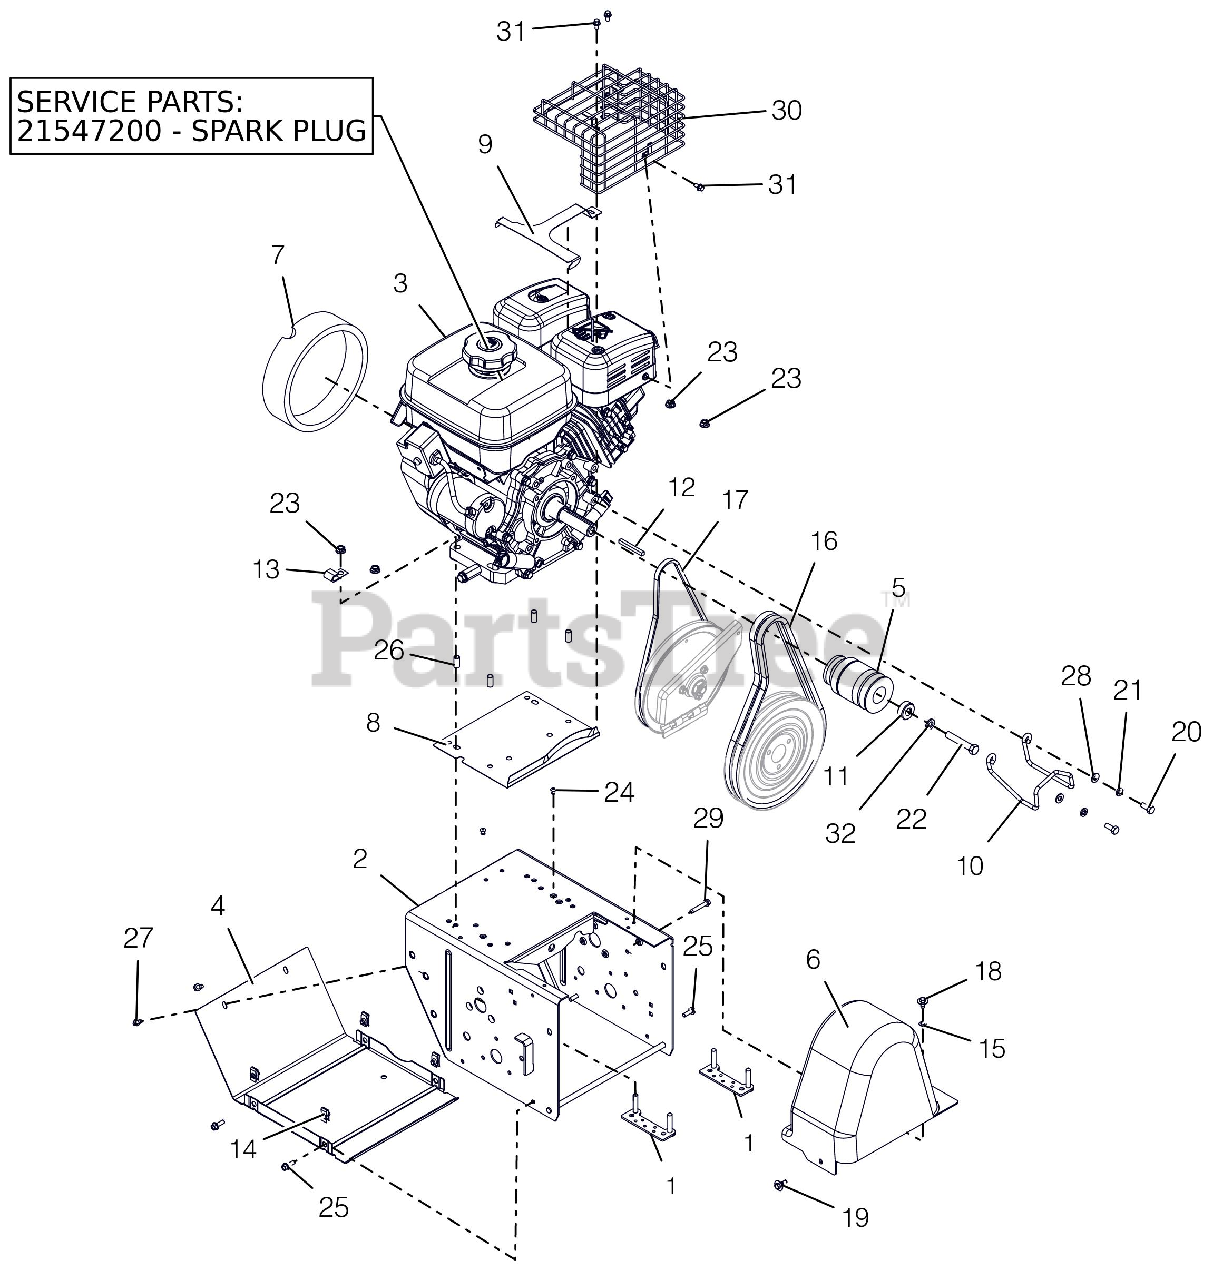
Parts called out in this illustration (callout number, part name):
1	STRAP, ENGINE BOLT-LARGE BRIGG
2	FRAME, MAIN - PRO (WELDMENT)
3	ENGINE,SUBARU EX27 AS 120V
3	PLUG, SPARK SUBARU
4	COVER, BOTTOM
5	SHEAVE, SUBARU EX27
6	COVER, BELT-TALL PRO
7	FOAM COVER, RECOIL-SUBARU
8	BAFFLE, WATER - LARGE BLOCK
9	GUARD, SNOW-SUBARU
10	FINGER, BELT
11	BSHG-SPACER .47X1.25X.50
12	KEY .25X.25X2.25
13	J-CLAMP
14	NUT-RTNR .25-20X.56
15	NUT-PUSH .25X.50 O.D.
16	V-BELT, HA-RAW EDGE (SET)
17	V-BELT, 3L-RAW EDGE
18	SCR-TAP .25-20X.50 LGHWH TR YZ
19	SCR-TAP .25-20X.5 CAPTIVE
20	BLT-HEX .31-24X.75 YWZC GR5
21	WSHR-LK .312X.097 HVY YWZC
22	BLT-HEX .44-20X2.50 GR5 YWZC
23	@NUT-LK-CTR-FLG .31-18 YZ GR F
24	RVT-POP .187 YZ
25	BLT-HEX .25-20X.75 HWH YZ GR5
26	BSHG-SLV .325X.400X.795
27	SCR-TAP .25-20X.50 HWH TR YWZ
28	@WSHR-FL-STL.344X.688X.065YWZC
29	@SCR-TAP .25-20X1.50 HWH TR YZ
30	MUFFLER GUARD, SUB EX270JO930
31	BLT-SERHFWH M6X1.0X12 8.8 CZ
32	@WSHR-LK .44X.109 REG YWZC
